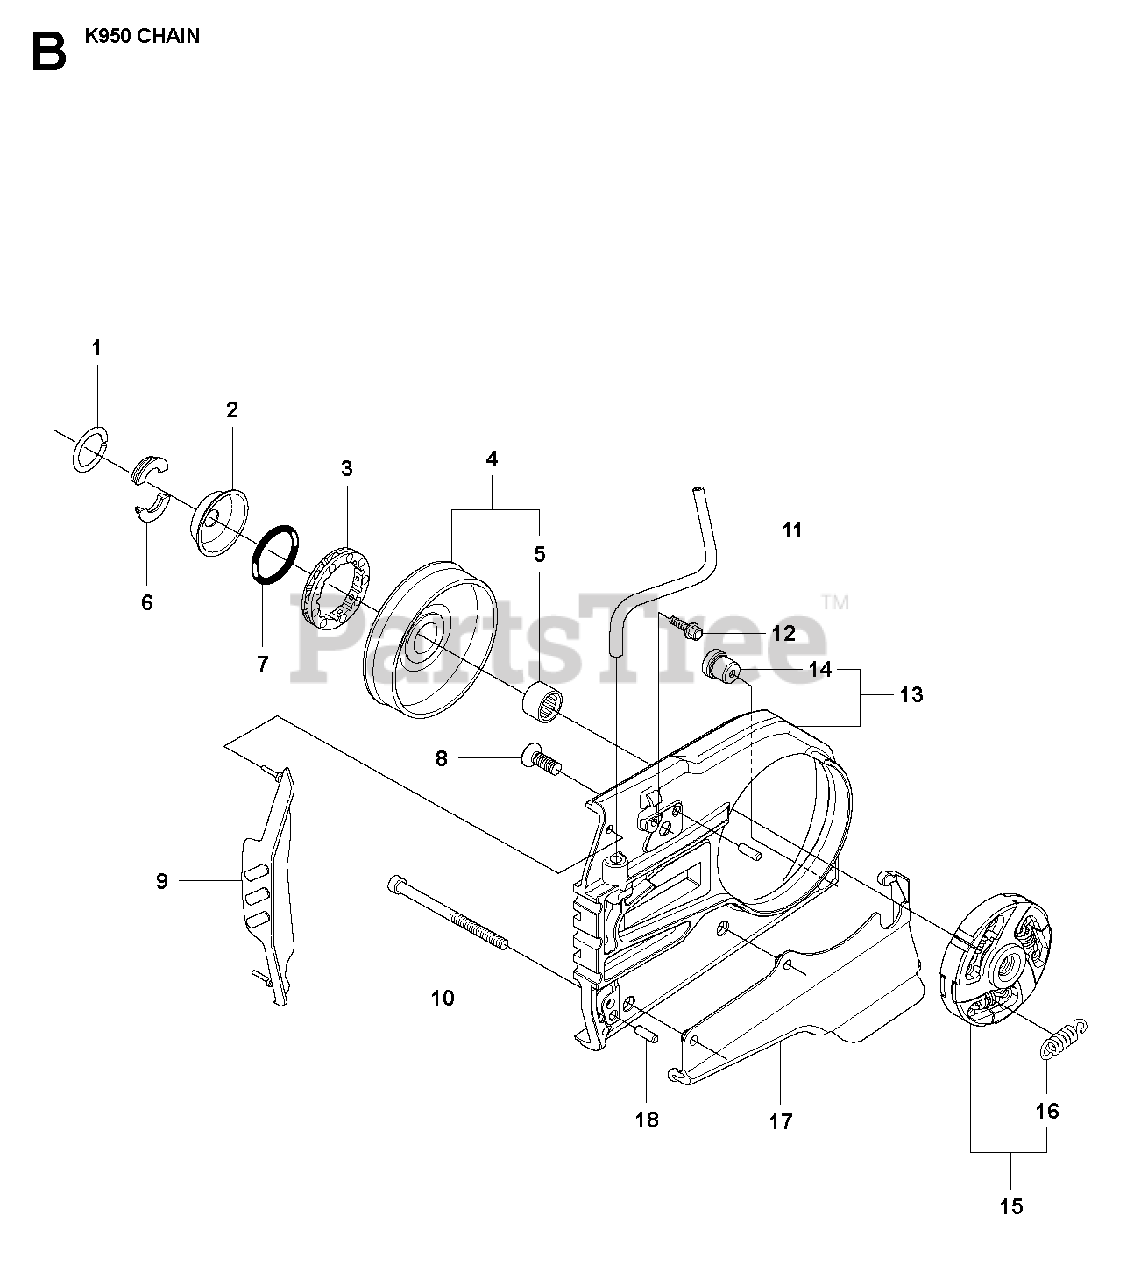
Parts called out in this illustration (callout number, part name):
1	RETAINER RING
5	NEEDLE BEARING
8	SCREW IHCSFM
10	SCREW IHSCFM
12	SCREW EHHFM
16	CLUTCH SPRING
18	PARALLEL PIN
